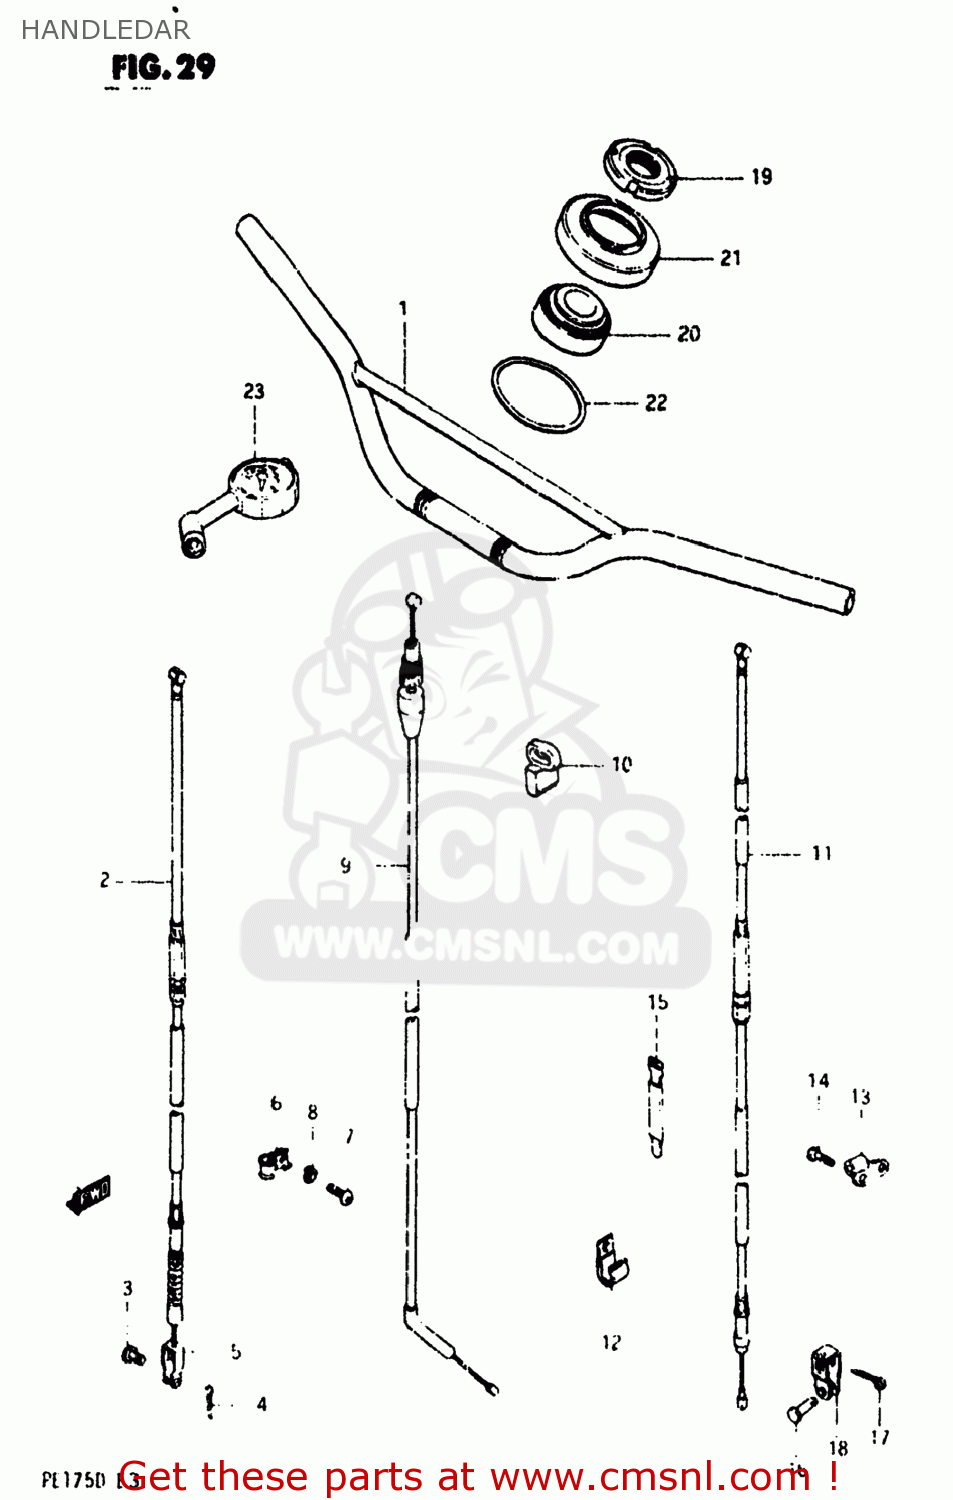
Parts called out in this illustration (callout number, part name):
1	HANDLEBAR
2	CABLE,FR BRAKE
3	PIN(L:13.5)
4	PIN
5	BRAKE CABLE HOOK
6	GUIDE,CABLE
7	SCREW
8	LOCK WASHER
9	CABLE ASSEMBLY,THROTTLE
10	GUIDE,CLUTCH CABLE
11	CABLE,CLUTCH
12	CLAMP
13	STOPPER,CLUTCH CABLE
14	SCREW
15	CLAMP
16	PIN(L:13)
17	PIN
18	HOOK,CLUTCH CABLE
19	NUT,STEERING STEM(25X44X10)
20	TAPER,ROLLER BEARING
21	DUST SEAL,STEERING UPR
22	O RING(D:3.53,ID:69.44)
23	GAUGE ASSY,AIR PRESSURE
